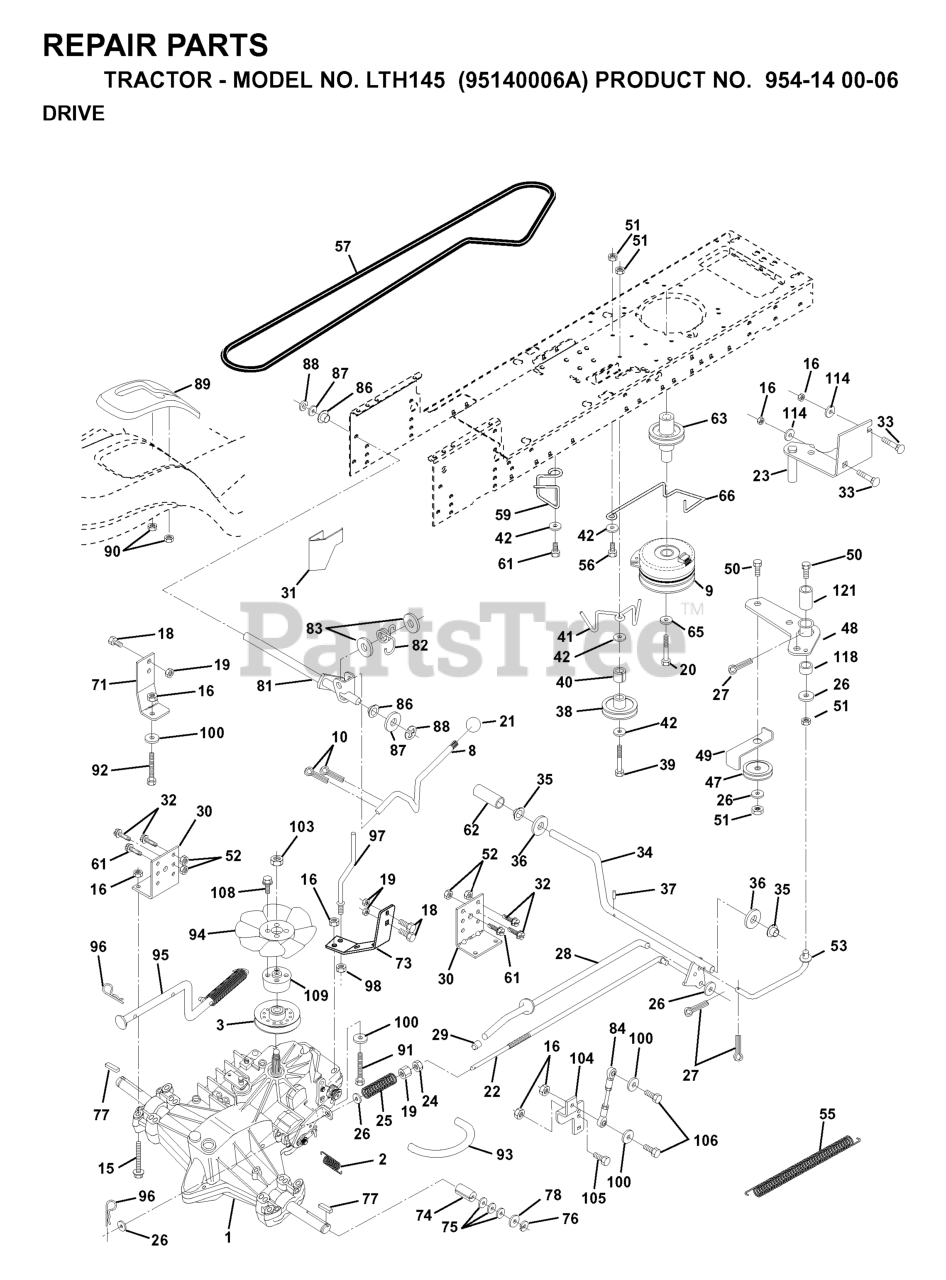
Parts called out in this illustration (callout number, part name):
1	TRANSAXLE.HYDRO.319-0500.LR
2	SPRING BRAKE
3	PULLEY.4.20.HYDRO
8	ROD SHIFT FENDER
9	CLUTCH.ELECT.EVX.
10	PIN COTTER
15	BOLT HEX 5/16-18 GR 5
16	NUT.71038.31-18.HEX.NYLOCK
19	NUT
20	BOLT HEX
21	KNOB.DUCKHEAD.1/2
22	ROD BRAKE HYDRO
23	BRACKET, ASM CLUTCH MTG
24	NUT
25	SPRING ROD LT
26	WASHER
27	COTTER PIN
28	ROD BRAKE PARK LT
29	PLUNGER CAP
30	BRACKET TRANSAXLE
31	KEEPER BELT LH
32	BOLT
33	RP BOLT 5/16-18 X3/4 ZN/YEL GR
34	SHAFT, FOOT PEDAL
35	BEARING.NYLON
37	DRIVE PIN
38	PULLEY.IDLER.FLAT
41	KEEPER, BELT IDLER
42	WASHER
47	IDLER PULLEY
48	BELLCRANK ASSEMBLY
49	RETAIN BELT
50	BOLT
52	LOCKNUT
53	LINK, CLUTCH LT
55	SPRING, RETURN LT
59	KEEPER CENTER SPAN
60	KEEPER,BLT ENG LT
61	SCREW
62	PEDAL COVER T
63	PULLEY, CLUTCH ELECT EVX
65	LOCKWASHER
66	KEEPER BELT ENGINE
71	STRAP TORQUE LH HYDRO
73	STRAP TORQUE RH HYDRO
74	SPACER SPLIT
77	SQUARE KEY
81	SHAFT ASM CROSS HYDRO
82	SPRING,TORSION
83	WASHER
84	ROD, TIE HYDRO
86	BUSHING.STEERING.ROD LTB-WSL
89	CONSOLE SHIFT
90	NUT.PUSH.3/16
91	BOLT.FIN HEX 5/16-18UNC X2 1/4
92	HEX BOLT
93	LINE FUEL HYD 4"
94	FAN 7" HYDRO
95	CONTROL ARM, BYPASS HYDRO
96	RETAINER M
97	KEEPER BELT RH
100	WASHER M
103	NUT.HEX.1/2-20
104	ARM, CONTROL HYDRO
106	BOLT.5/16-18X1-1/4 FULL.THREAD
109	ADAPTOR FAN HYDRO
114	Washer 11/32 x 3/4 x 14 Gauge
118	SPACER BELLCRANK
121	NYLINER CLUTCHING
